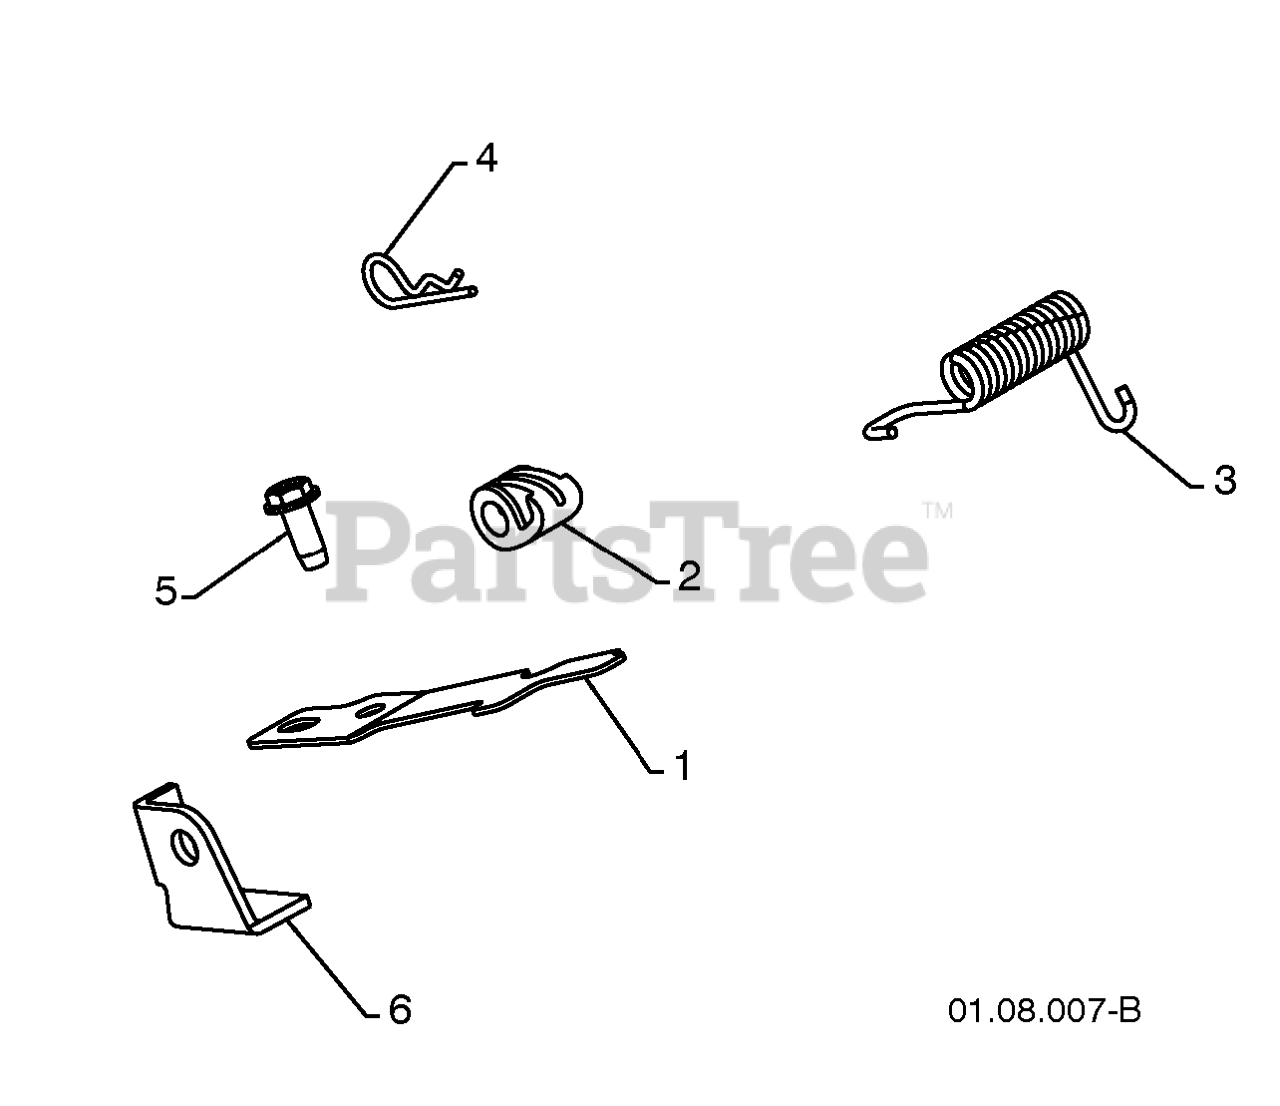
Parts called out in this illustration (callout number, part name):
1	RP SPRING.INTERLOCK
2	CAM.INTERLOCK.RELEASE
3	RP SPRING, TORSION
4	SPRING RETAINER
5	SCREW 14-20 X 5/8
6	STOP.INTERTLOCK.SPRING.
